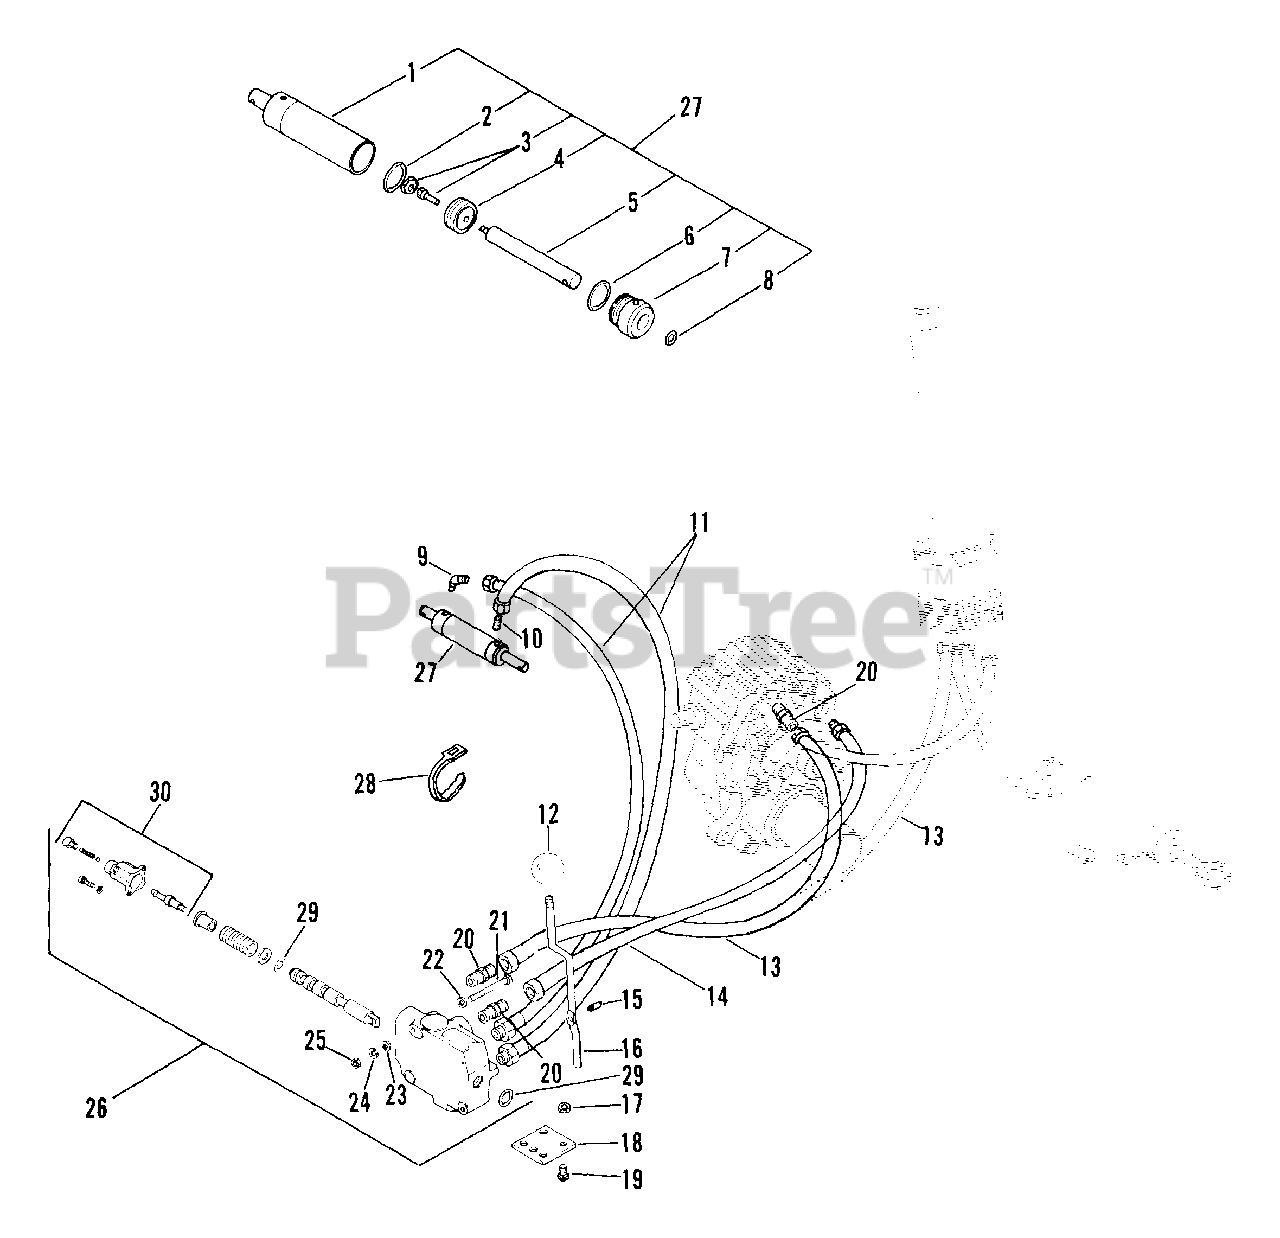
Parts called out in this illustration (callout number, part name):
1	CYLINDER
2	O-RING 1.625X2.000
2	SCR-SKH .38-24X1.00
3	NUT-LK .375-24 PL
4	PISTON
5	ROD
6	O-RING 1.937X2.125
7	ROD CAP
8	O-RING 1.000X1.250X
9	ADAPTER 45 9/16 TO 1/4
10	ADAPTER
11	HYDRAULIC HOSE
11	CONNECTOR - EXTENDED
12	KNOB-STEERING LOCK
13	HYDRAULIC HOSE
14	HYDRAULIC HOSE
15	PIN-GRV .250X.75 TP B PL
16	CONTROL ROD
17	NUT-FLG. .312-18 PL
18	PIVOT BRACKET
19	BLT-RDHDSQSHNK .31-18X.50 YZ
20	CONNECTOR
21	BLT-HEX .25-20X2.25 GR2
22	WSHR-FL-STL .250X.562X.125 PL
23	WSHR-FL-STL.281X.62X.065 PL
24	WSHR-LK .250X.077 HVY PL
25	NUT-HEX .250-20 PL
26	HYDRAULIC CONTROL VALVE
27	CYLINDER ASSEMBLY (LIFT)
28	CABLE TIE LG 7-3/4
29	SEAL KIT
30	DETENT CAP REPAIR KIT
